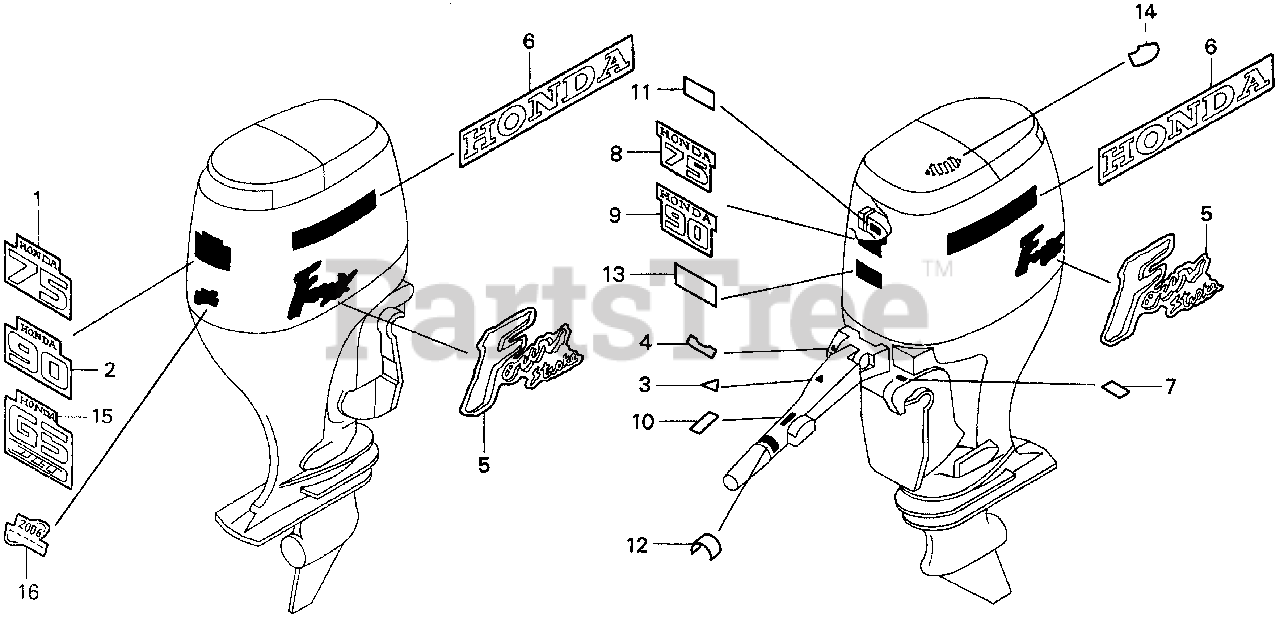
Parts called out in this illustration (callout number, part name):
2	MARK, RR. (BF90)
3	MARK, EMERGENCY SWITCH INDICATION (ENGLISH)
4	MARK, START (E)
5	MARK, SIDE
6	MARK, SIDE STRIPE
7	LABEL, SPECIFICATION (NMMA)
9	MARK, FR. EMBLEM
10	MARK, CHANGE (JAPANESE/ENGLISH)
11	LABEL, OIL CAUTION (ENGLISH)
12	MARK, THROTTLE (ENGLISH)
13	LABEL, CAUTION OPERATOR (ENGLISH)
14	MARK, EMERGENCY START (ENGLISH)
16	MARK, ENVIRONMENT (EPA 2006)
